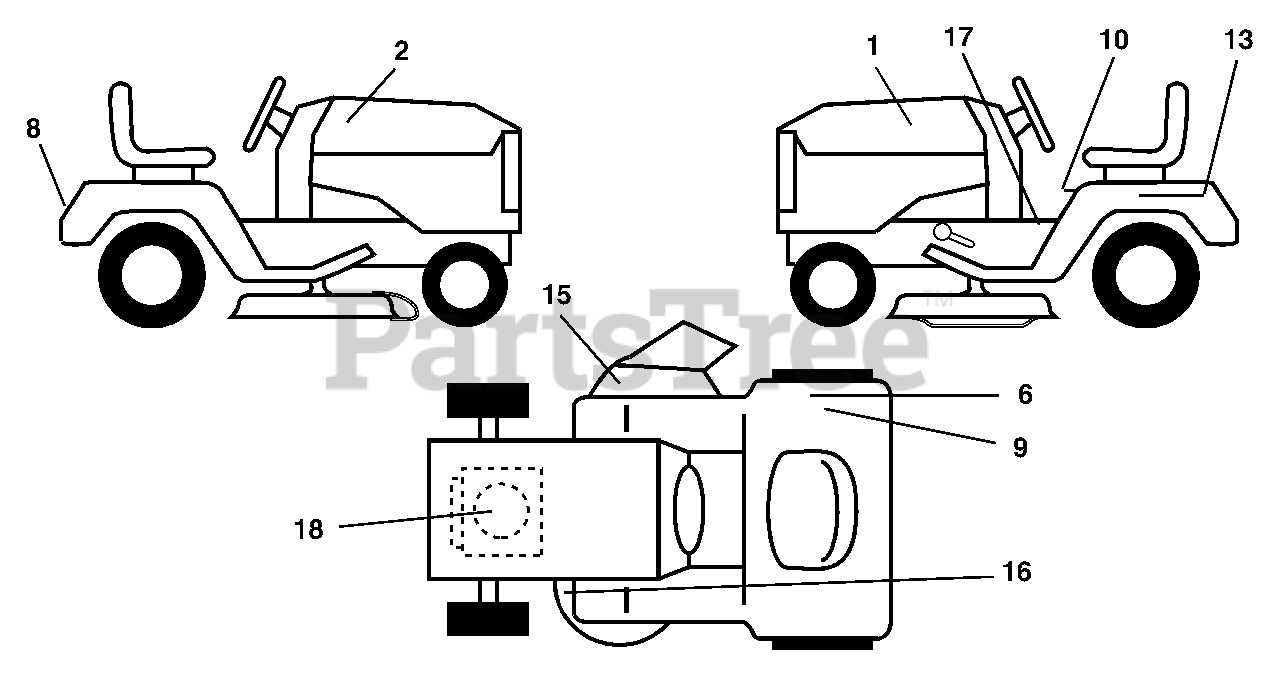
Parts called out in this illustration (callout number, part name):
1	Decal, Hood, L. H., Husqv.
2	Decal, Hood, R. H., Husqv.
6	Decal Europe Stand. CE Tractors
8	Decal, Logo, Fender
9	Decal, Certification,(French/Dutch)
10	Decal, Read Owner's Manual Symbols
13	Decal, Battery
15	Decal, Cutfinger
16	Decal, V-Belt Sch.
17	Decal, Operating Instructions Symbols
18	Decal, Engine
